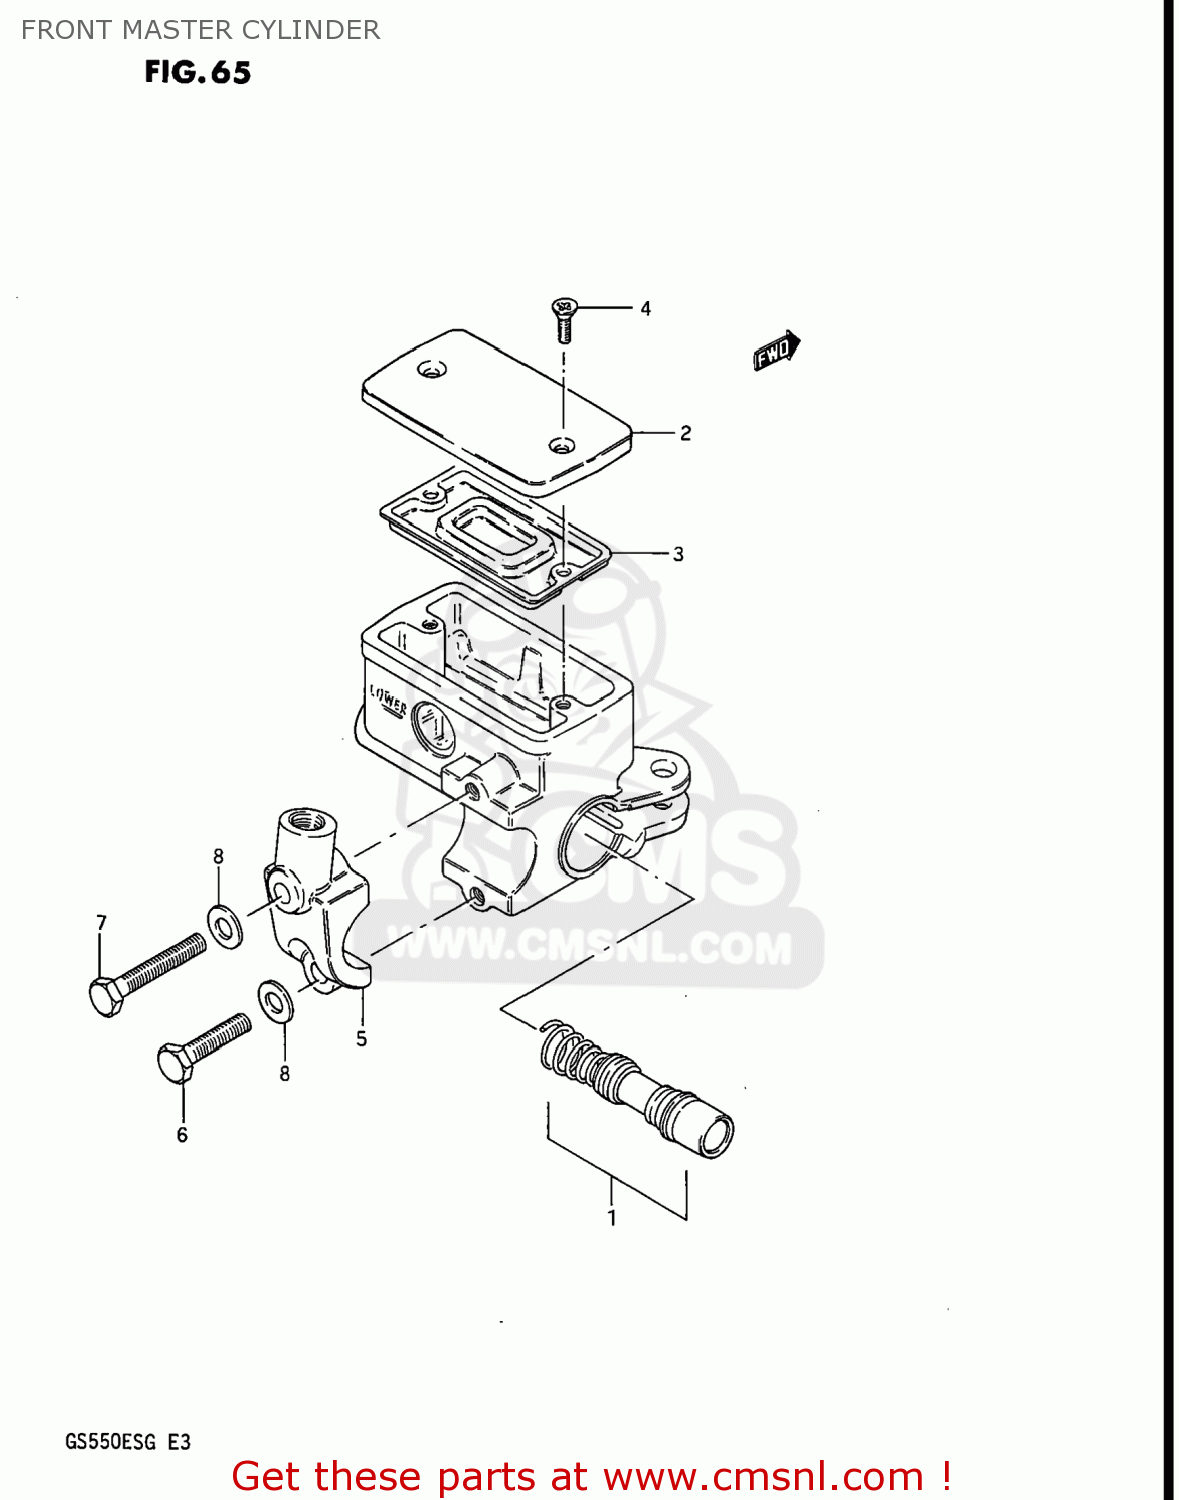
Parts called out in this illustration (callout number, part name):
1	PISTON & CUP SET
2	CAP
3	4
4	SCREW
5	HOLDER
6	BOLT
7	BOLT
8	WASHER
